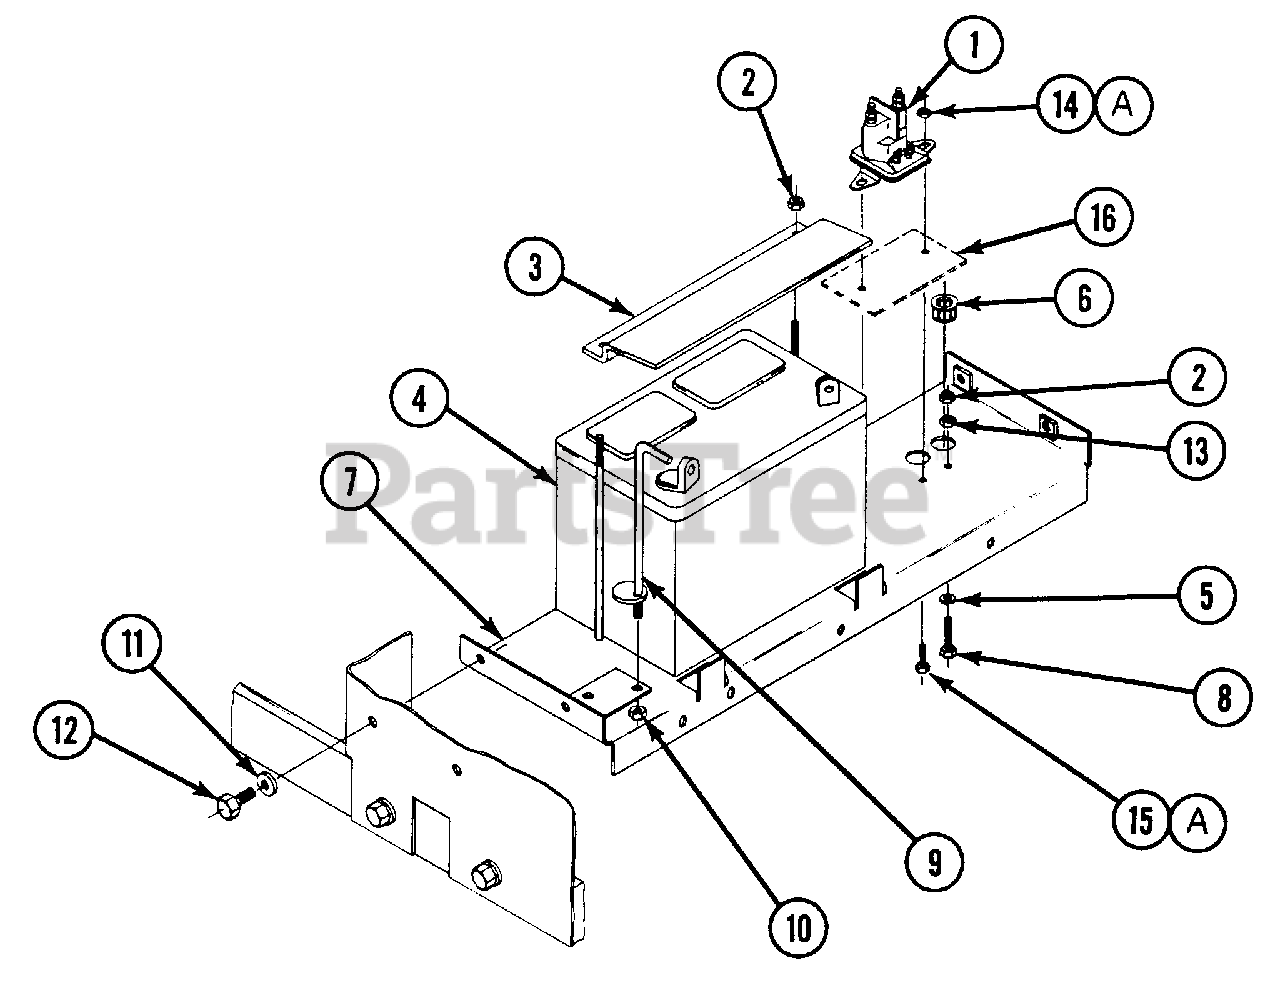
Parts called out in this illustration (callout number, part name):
1	SOLENOID, STARTER, 12 V, NON-GROUNDED
2	LOCKNUT, HEX, 1/4-20 W/NYLOC
3	BATTERY HOLD DOWN PROTECTOR
4	BATTERY, 12 VOLT, BCI GROUP VI
5	LOCKWASHER, 1/4 STD, SPLIT SPRING
6	BUSHINGS, PLASTICS WIRE PROTECTOR
7	BATTERY MOUNT WELDMENT
7	BATTERY MOUNT WELDMENT, JOYSTICK
8	CAPSCREW, HEX, 1/4-20 X 1, GRADE 5
9	DUMP-VALVE HANDLE WELDMENT
10	LOCKNUT, HEX, 5/16-18 W/NYLOC
11	LOCKWASHER, 3/8 HEAVY, SPLIT SPRING
12	CAPSCREW, 3/8-16 X 1, GRADE 5
13	NUTS HEX, 1/4-20
14	NUTS HEX, 1/4-20
14A	NUT, NYLON HEX, 1/4-20
15	CAPSCREW, HEX, 1/4-20 X 3/4 GRADE 5
15A	CAPSCREW, HEX, NYLON, 1/4-20 X 3/4
16	INSULATOR PLATE, PLASTIC
